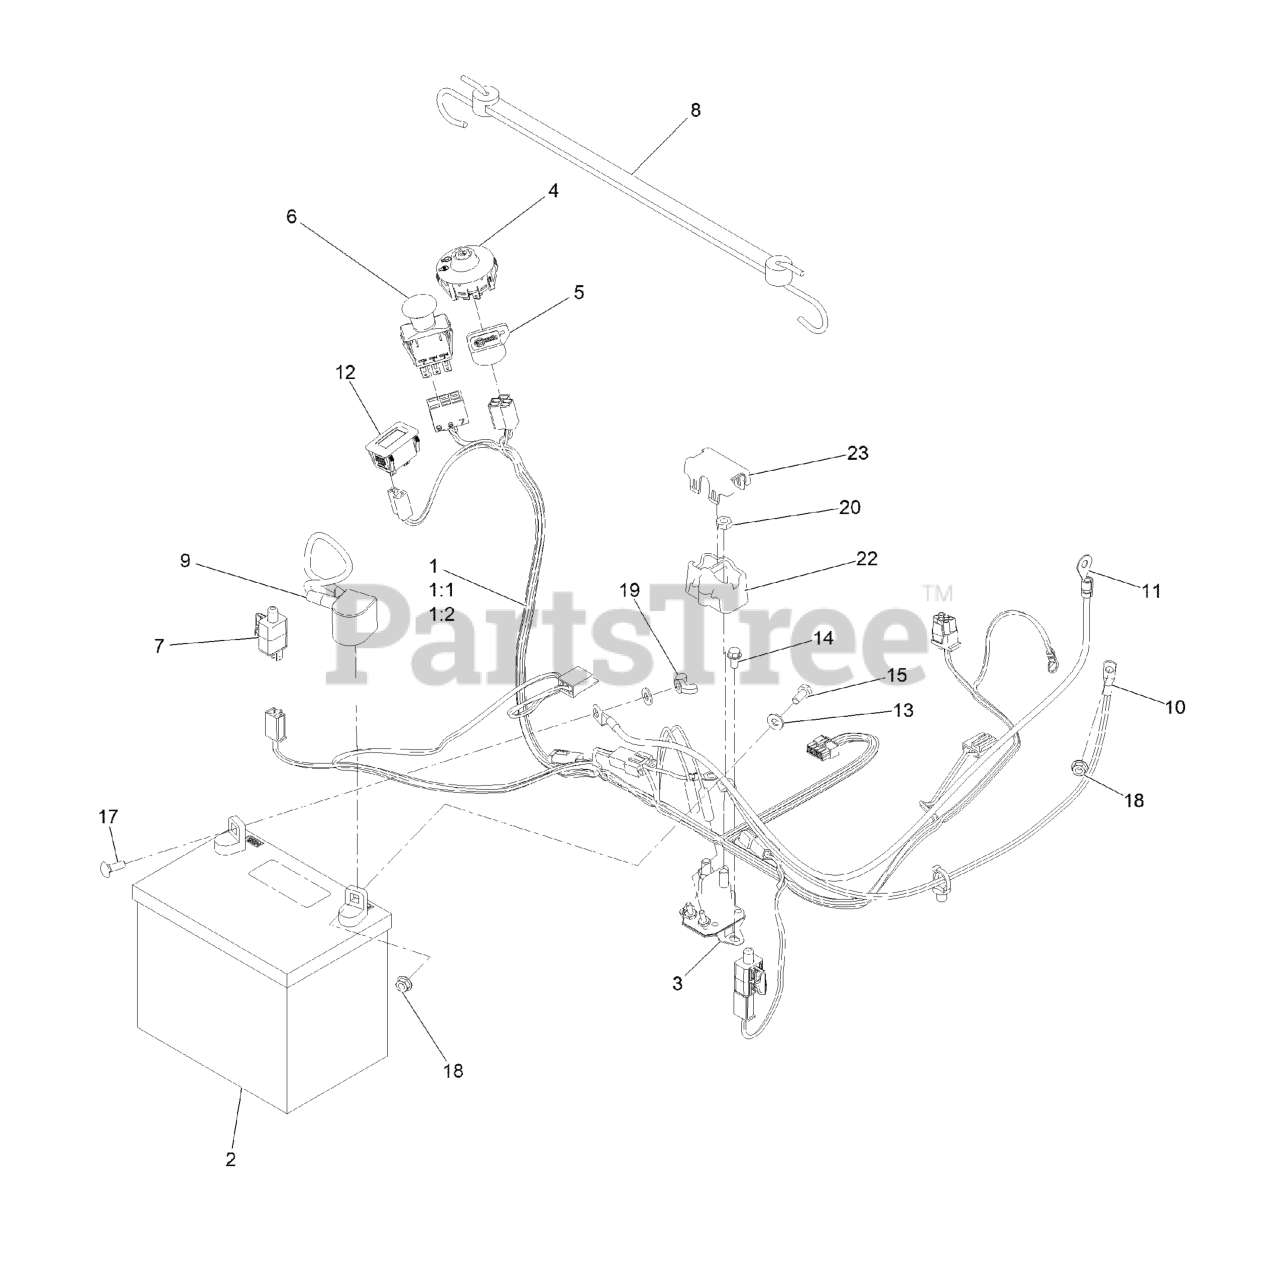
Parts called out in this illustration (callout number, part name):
1	HARNESS-WIRE
1:1	FUSE-BLADE, 15 AMP
1:2	FUSE-BLADE, 25 AMP
2	BATTERY
3	SOLENOID
4	SWITCH-IGNITION
5	KEY-IGNITION
6	SWITCH-PTO
8	STRAP-RUBBER
9	CABLE-BATTERY, POS
10	CABLE-BATTERY, RED (8 GAUGE)
11	CABLE-BATTERY, BLACK
12	HOURMETER
13	WASHER-FLAT
14	SCREW-HWH
15	SCREW-HH
17	BOLT-CARR
19	NUT-WING
20	NUT-JAM
22	COVER-SOLENOID
23	CAP-SOLENOID
